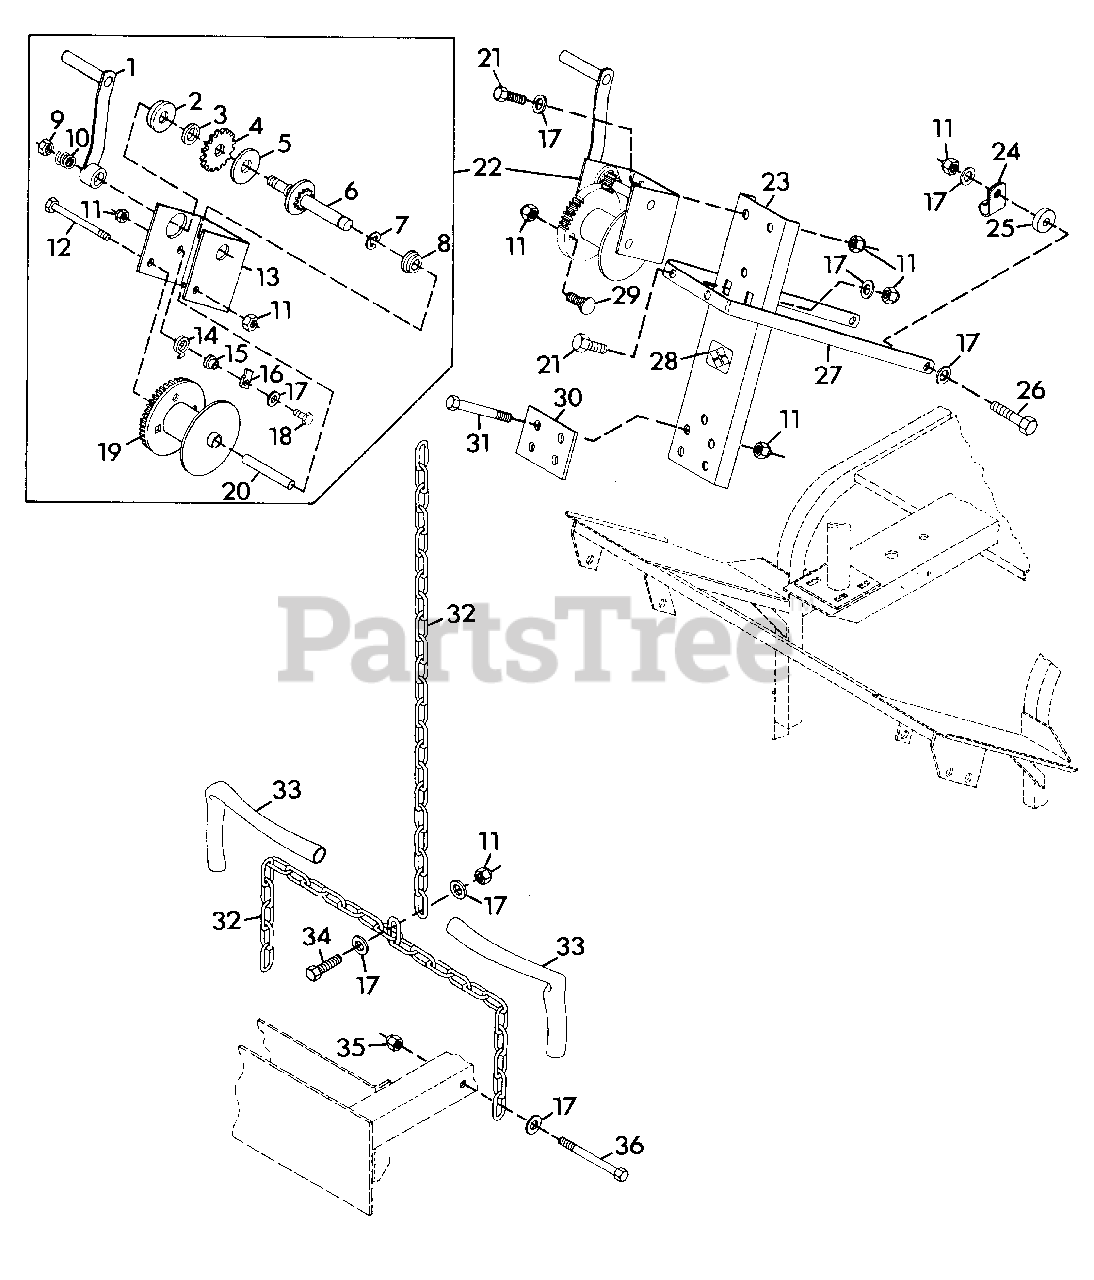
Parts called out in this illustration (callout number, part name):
1	Handle, Winch
2	Bushing, Shaft
3	Washer, Pressure
4	Wheel, Ratchet
5	Plate, Pressure
6	Shaft, Drive
7	E-Ring, .625 Shaft
8	Bushing, Shaft
9	Nut, Handle
10	Spring, Handle
11	Nut, Lock 3/8-16
12	Bolt, Hex 3/8-16x4.50
13	Base, Winch
14	Spring, Ratchet
15	Spacer, Ratchet
16	Pawl, Ratchet
17	Washer, Flat .406x.812x.065
18	Bolt, Ratchet
19	Reel, Winch
20	Spacer, Tubing
21	Bolt, Hex 3/8-16x1
22	Winch
23	Channel, Winch Lift
24	Clamp, Nylon
25	Spacer
26	Bolt, Hex 3/8-16x1.375
27	Brace
28	Decal, Commercial Front
29	Bolt, 3/8-16x.875 Rd Hd Sq Nk
30	Plate, Channel Clamp
31	Bolt, Hex 3/8-16x2.5
32	Chain, Mower Lift
33	Tubing
34	Bolt, Hex 3/8-16x1.125
35	Nut, Lock 5/16-24
36	Bolt, Hex 5/16-24x2.75
